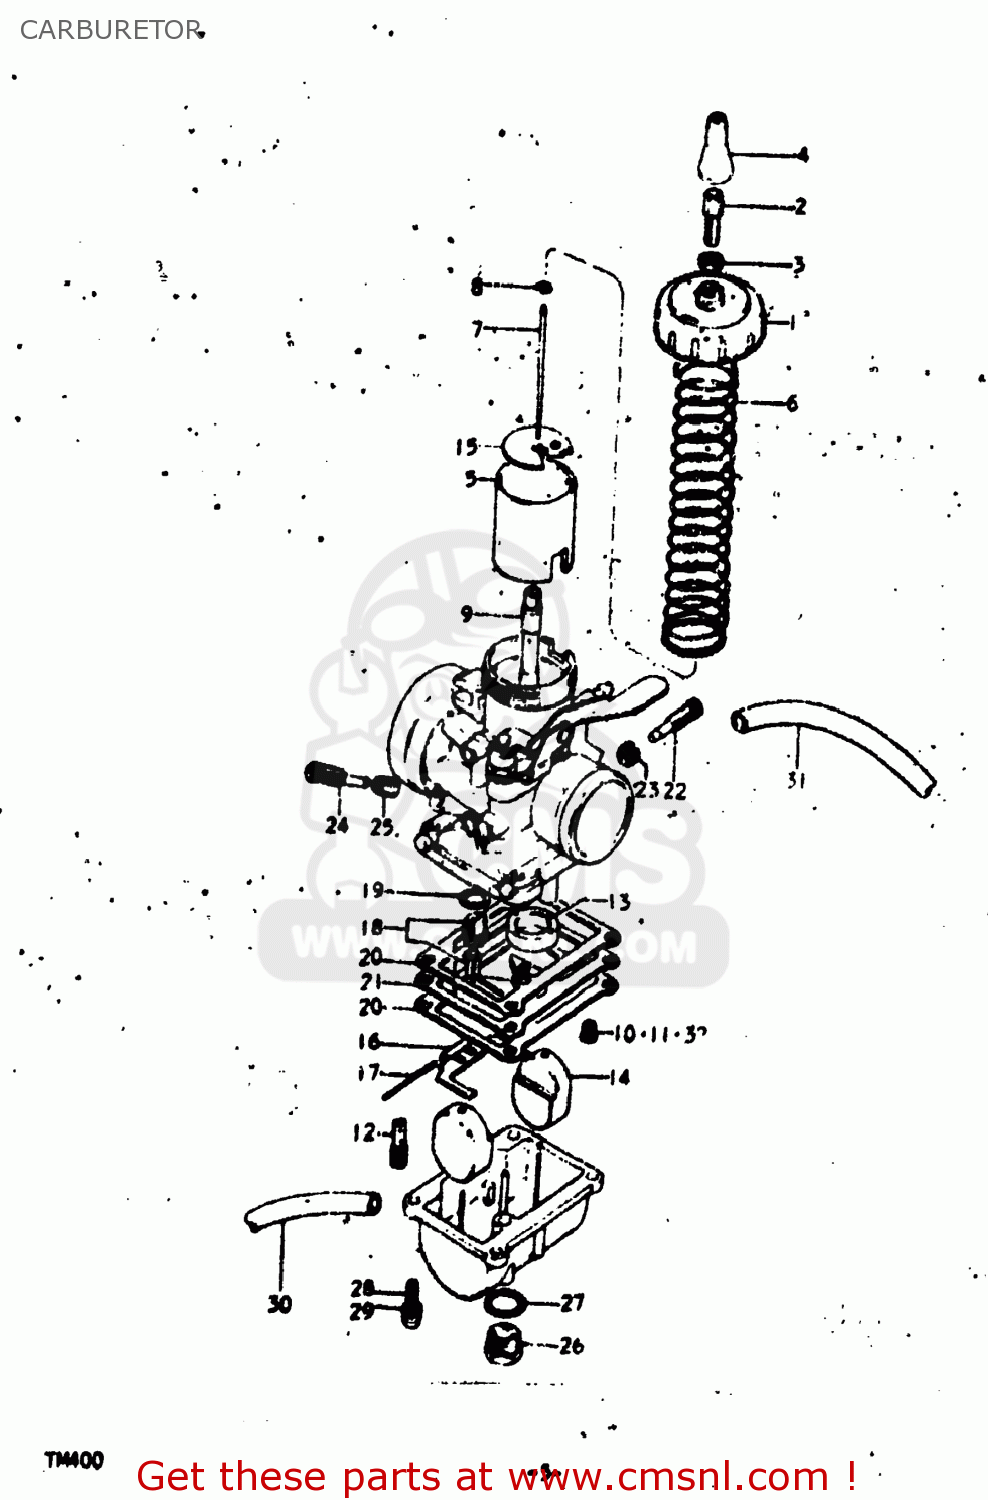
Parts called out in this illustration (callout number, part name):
0	CARBURETOR ASSEMBLY
1	CAP,MIXING CHAMBER
2	ADJUSTER,CABLE
3	NUT
4	CAP
5	VALVE,THROTTLE
6	SPRING
7	NEEDLE JET
8	CLIP
9	JET,NEEDLE
10	JET
11	JET
12	JET,PILOT(35)
13	RING
14	FLOAT
15	PLATE,THROTTLE VALVE
16	ARM,FLOAT
17	PIN,FLOAT
18	VALVE ASSY,NEEDLE
19	GASKET,MAIN JET HOLDER (NAS)
20	GASKET,FLOAT CHAMBER
21	PLATE
22	ADJUSTER
23	NUT, STOP SCREW
24	SCREW,PILOT AIR
25	SPRING
26	SCREW,DRAIN
27	GASKET,DRAIN PLUG
28	SCREW
29	LOCK WASHER
30	HOSE
31	HOSE
32	JET
